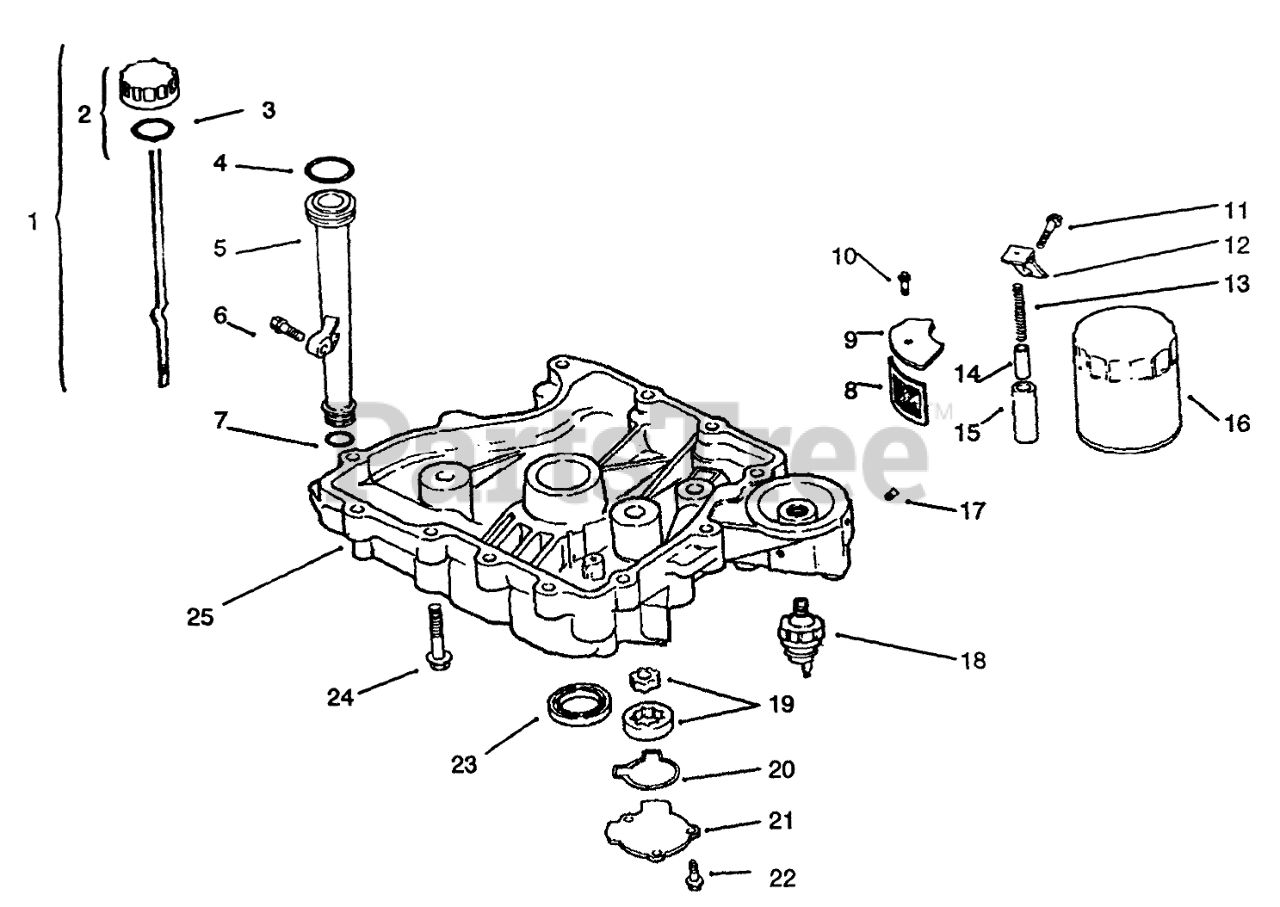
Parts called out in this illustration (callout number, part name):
1	Dipstick INC 2-3 (Only On: 72042, 72063, 72062, 72043)
2	Kit-Oil Cap INC 3 (Only On: 72042 72063, 72062, 72043)
3	O-Ring-Fill Cap (Only On: 72042, 72063, 72062, 72043)
4	O-Ring-Upper Fill Tube (Only On: 72042, 72063, 72062, 72043)
5	Tube-Oil Fill (Only On: 72042, 72063, 72062, 72043)
6	Screw M5x0.8x20 (Only On: 72042, 72063, 72062, 72043)
7	O-Ring-Lower Fill Tube (Only On: 72042, 72063, 72062, 72043)
8	Screen-Oil Pickup (Only On: 72042, 72063, 72062, 72043)
9	Cover-Oil Pickup Screen (Only On: 72042, 72063, 72062, 72043)
10	Screw M5x0.8x16 (Only On: 72042, 72063, 72062, 72043)
11	Screw M10x1.5x25 (Only On: 72042, 72063, 72062, 72043)
12	Bracket-Oil Pump Relief (Only On: 72042, 72063, 72062, 72043)
13	Spring-Oil Relief Valve (Only On: 72042, 72063, 72062, 72043)
14	Piston-Oil Relief Valve (Only On: 72042, 72063, 72062, 72043)
15	Body-Oil Relief Valve (Only On: 72042, 72063, 72062, 72043)
16	Filter-Oil (Only On: 72042, 72063, 72062, 72043)
17	Plug-SH 3/8 NPTF (Only On: 72042, 72063, 72062, 72043)
18	Switch-Oil Pressure (Only On: 72042, 72063, 72062, 72043)
19	Pump-Oil (Only On: 72042, 72063, 72062, 72043)
20	O-Ring-Oil Pump Cover (Only On: 72042, 72063, 72062, 72043)
21	Cover-Oil Pump (Only On: 72042, 72063, 72062, 72043)
22	Screw M5x0.8x16 (Only On: 72042, 72063, 72062, 72043)
23	Seal-Crankshaft (Only On: 72042, 72063, 72062, 72043)
24	Screw M8x1.25x45 (Only On: 72042, 72063, 72062, 72043)
25	Pan-Oil (Only On: 72042, 72063, 72062, 72043)
